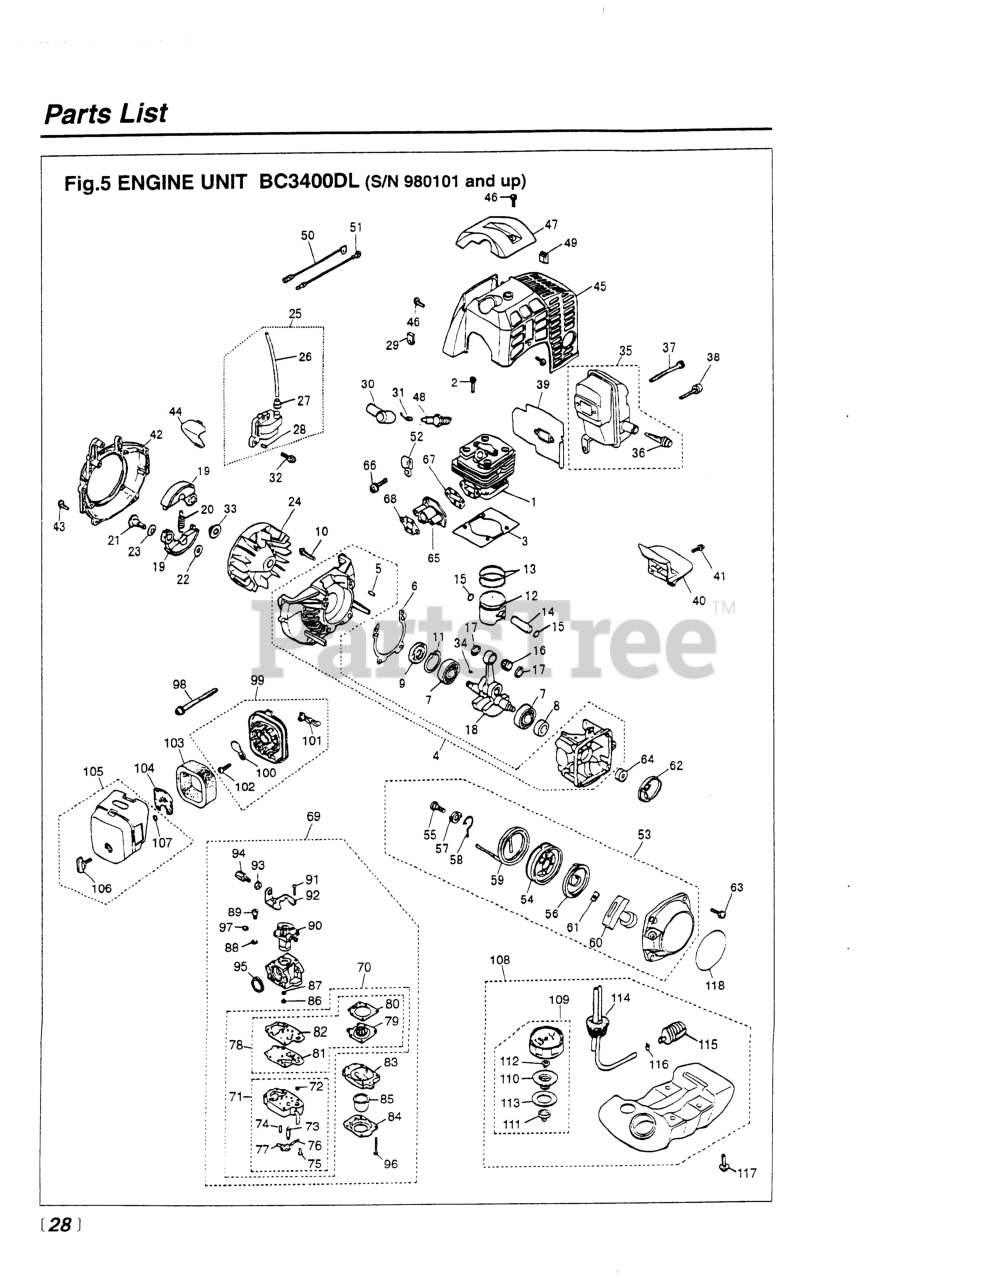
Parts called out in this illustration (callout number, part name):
1	CYLINDER
2	BOLT M5 x 20 (RPLS -12280)
3	GASKET, BASE
4	CRANKCASE COMPL (USE -21101)
5	PIN
6	GASKET
8	SEAL
9	SEAL, OIL (RPLS 1200-21220)
10	BOLT, M5 X 30
11	RING, SNAP, M32 x 1.2
12	PISTON
13	RING, PISTON
14	PIN, PISTON
15	RING, SNAP
16	BEARING
17	WASHER
18	CRANKSHAFT COMPL
19	SHOE, CLUTCH (RPLS -51110)
20	SPRING
21	SCREW
22	WASHER
23	WASHER (RPLS. -51240)
24	ROTOR
25	COIL ASSEMBLY
29	GROMMET
31	SPRING
32	BOLT, M4 x 22
34	KEY
35	MUFFLER ASSEMBLY
36	ARRESTER (RPLS 5850-15140)
37	BOLT, M5 x 60
38	BOLT (REPLACES 01252-30514)
40	PLATE (USE-15221)
41	SCREW,M5 X 14 (RPLS 1400-15510
43	BOLT M5 x 20 (RPLS -12280)
45	COVER
46	SCREW M5 x 12
47	GUARD
50	CORD
51	CORD, EARTH
52	CLAMP
53	RECOIL ASSEMBLY
54	REEL
55	SCREW
56	SPRING, SPIRAL
57	COLLAR
58	ARM
59	ROPE (USE 4810-75160)
60	KNOB
61	PLATE, STOPPER
62	PULLEY
63	SCREW, M6 x 14
66	SCREW, M5 X 20 (USE 5516-85510
67	GASKET, INSULATOR
68	GASKET, CARBURETOR
69	CARBURETOR ASSEMBLY
71	BODY, PUMP
72	SCREEN
73	VALVE, INLET
75	SCREW
76	PIN
77	LEVER
79	DIAPHRAGM
80	GASKET, DIAPHRAGM
81	DIAPHRAGM, PUMP
82	GASKET, PUMP
83	BODY, PURGE
84	COVER, PUMP
85	PUMP, PRIMING
86	JET
87	RING, O
88	RING
89	SWIVEL
90	VALVE ASSY
91	SCREW
93	NUT, CABLE ADJUSTER
94	SCREW, CABLE ADJUSTER
95	RING, PACKING
96	SCREW
97	WASHER
99	BODY ASSEMBLY
100	PLATE, CHOKE
101	LEVER, CHOKE
102	SCREW (REPLACES 50030272)
103	ELEMENT
104	SCREEN
106	KNOB (RPLS -82220)
107	RING
110	HOLDER (USE -85300)
111	HOLDER, CAP
112	VALVE (NLA WHEN OUT)
113	PACKING
114	PIPE COMPLETE
115	FILTER ASSY
116	CLIP (REPLACES 2841-31280)
117	SCREW, M5 X 22
118	LABEL, RECOIL
